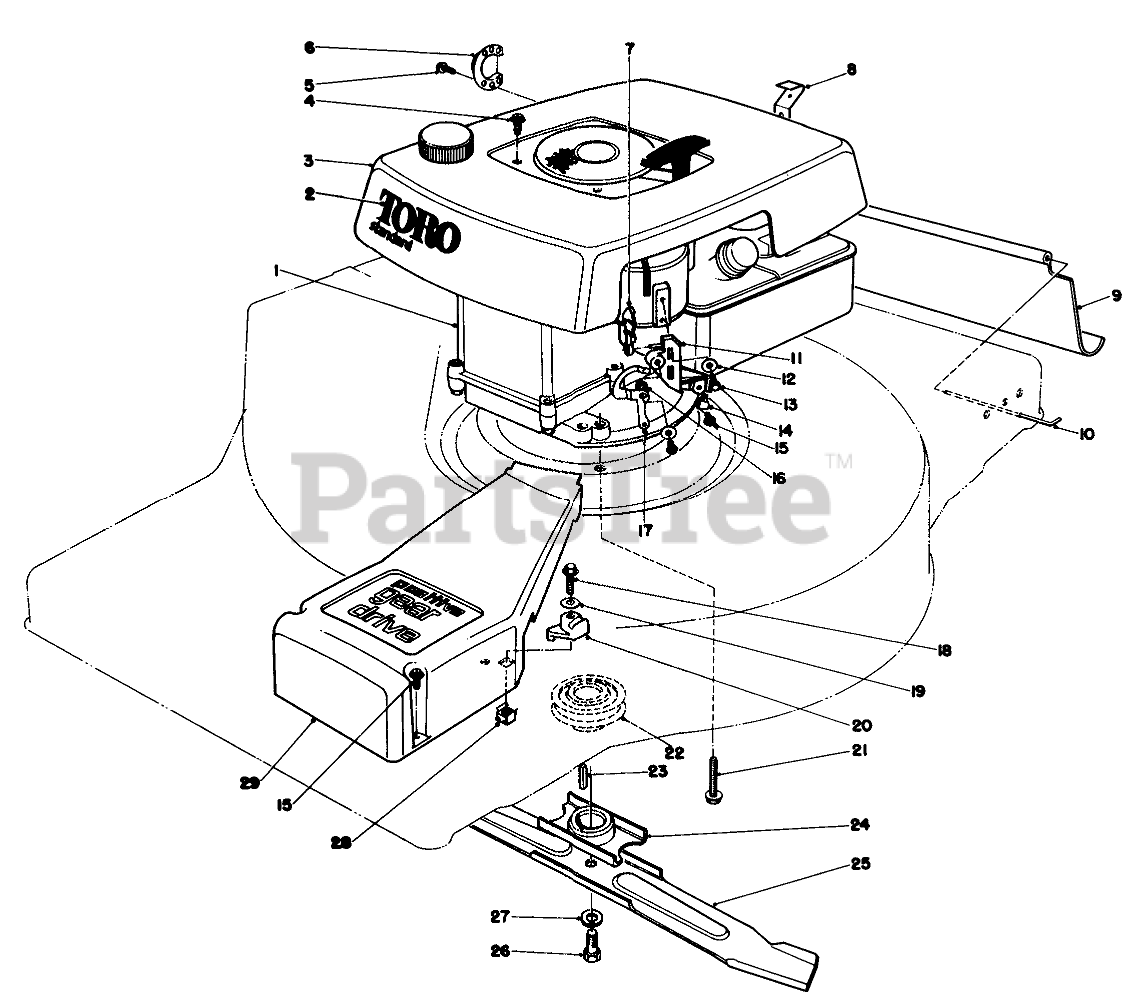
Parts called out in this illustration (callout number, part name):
1	Engine
2	Decal Shroud
3	SHROUD
4	8X1/2 SELF TAP SCREW
5	SCREW W/ENGINE
6	Deflector
7	INTERLOCK LEVER
8	Bracket Control
9	SAF SHIELD REAR
10	SHIELD ROD
11	CABLE & PIVOT BLOCK
12	WASHER-FLAT
13	SCREW-SHWH
14	CLAMP
15	SCREW-HWHTF
16	BUSHING
17	CAM INTERLOCK
19	WASHER-FLAT
20	CABLE BOSS
21	SCREW-HWHTF
22	DRIVER PULLEY
23	KEY-SQUARE
24	Blade Retailer
25	Blade
26	SPECIAL SCREW
27	WASHER-LOCK
28	SPEED NUT
29	Belt Cover
